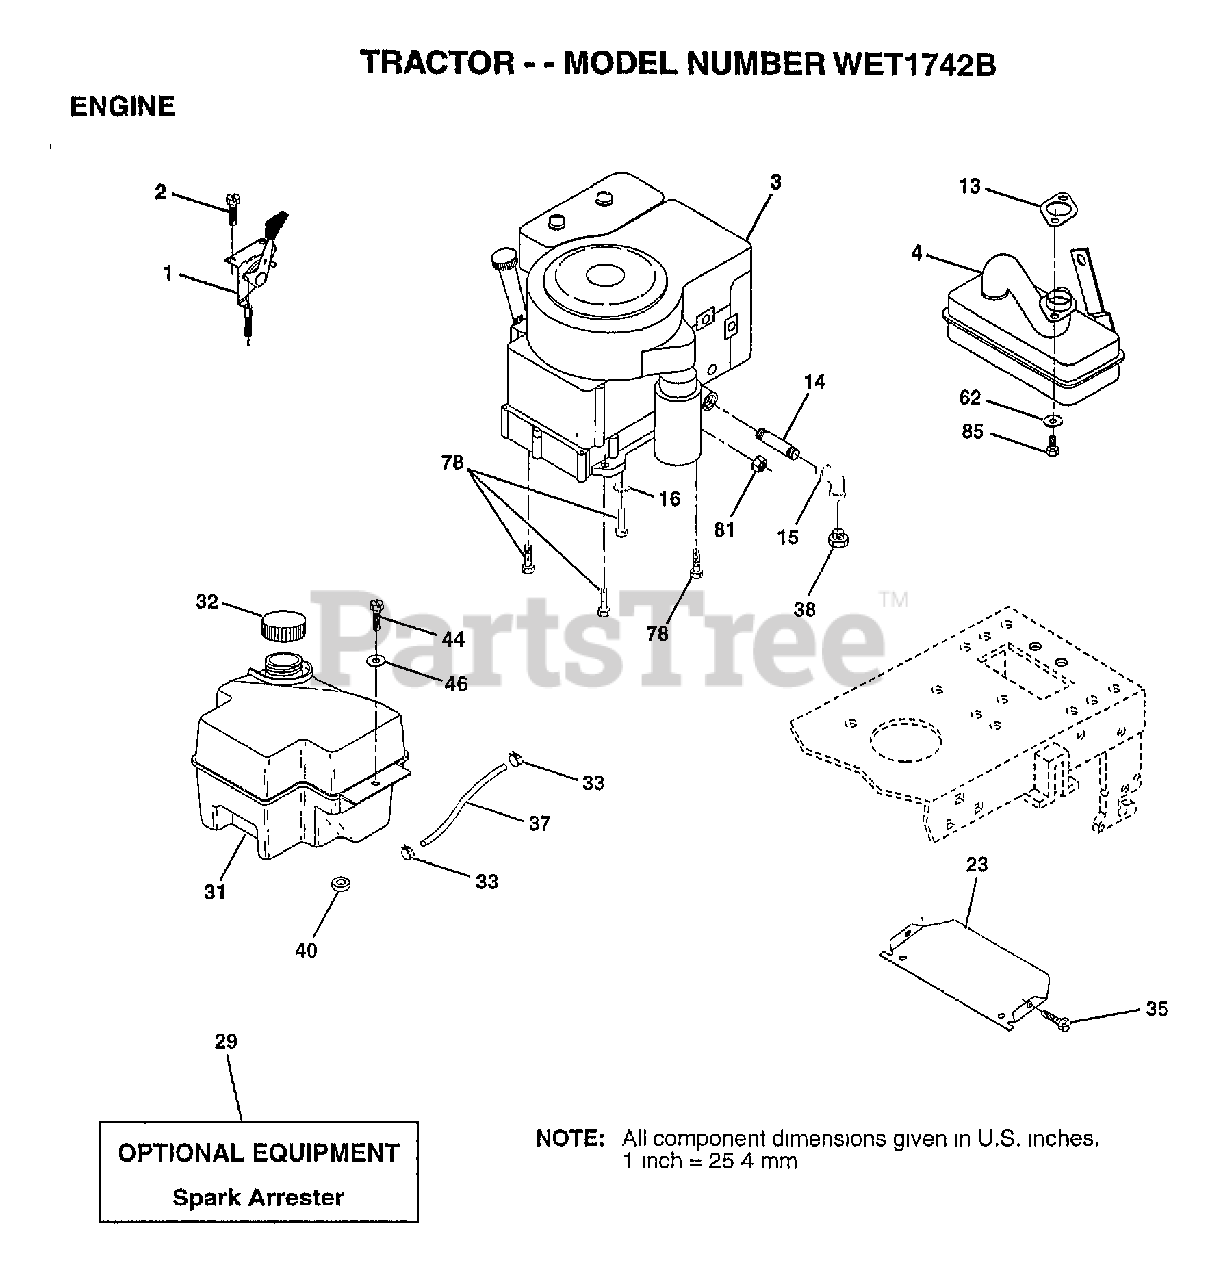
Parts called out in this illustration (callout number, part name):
1	CONTROL THROTTLE
2	SCREW LT
4	MUFFLER
13	GASKET MUFFLE TEC
14	PIPE NIPPLE LT
15	ELBOW
16	LOCKWASHER
23	SHIELD-HEAT
32	CAP ASM FUEL
33	HOSE CLAMP
35	SCREW
37	LINE FUEL
44	SCREW HEX CRT
46	WASHER
62	LOCKWASHER
78	SCREW
81	NUT
85	SCREW HEX HD CAP
